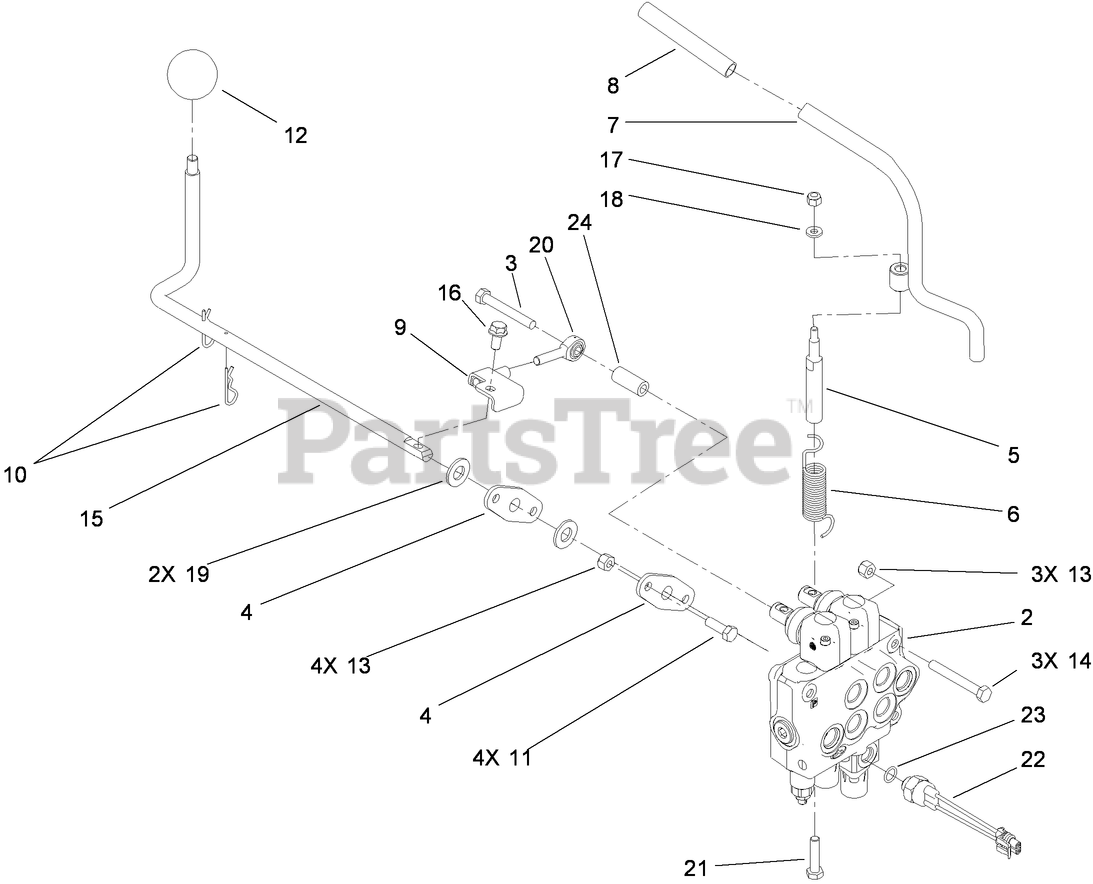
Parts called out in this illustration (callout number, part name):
2	HYD VALVE ASM
3	SCREW-HH
4	BEARING-WHEEL, FRICTION
5	SPACER-HIFLO
6	SPRING-TORSION
7	LEVER-AUXILIARY
8	GRIP-RUBBER
9	CONTROL ASM
10	PIN-HAIR
11	SCREW-HH
13	NUT-LOCK, NI
14	SCREW-HH
15	ROD-LEVER, CYLINDER
16	SCREW-HHF
17	NUT-LOCK, NI
18	WASHER-FLAT
19	WASHER-FLAT
20	BEARING-ROD END
21	SCREW
22	SWITCH-BALL
23	O-RING
24	SPACER
